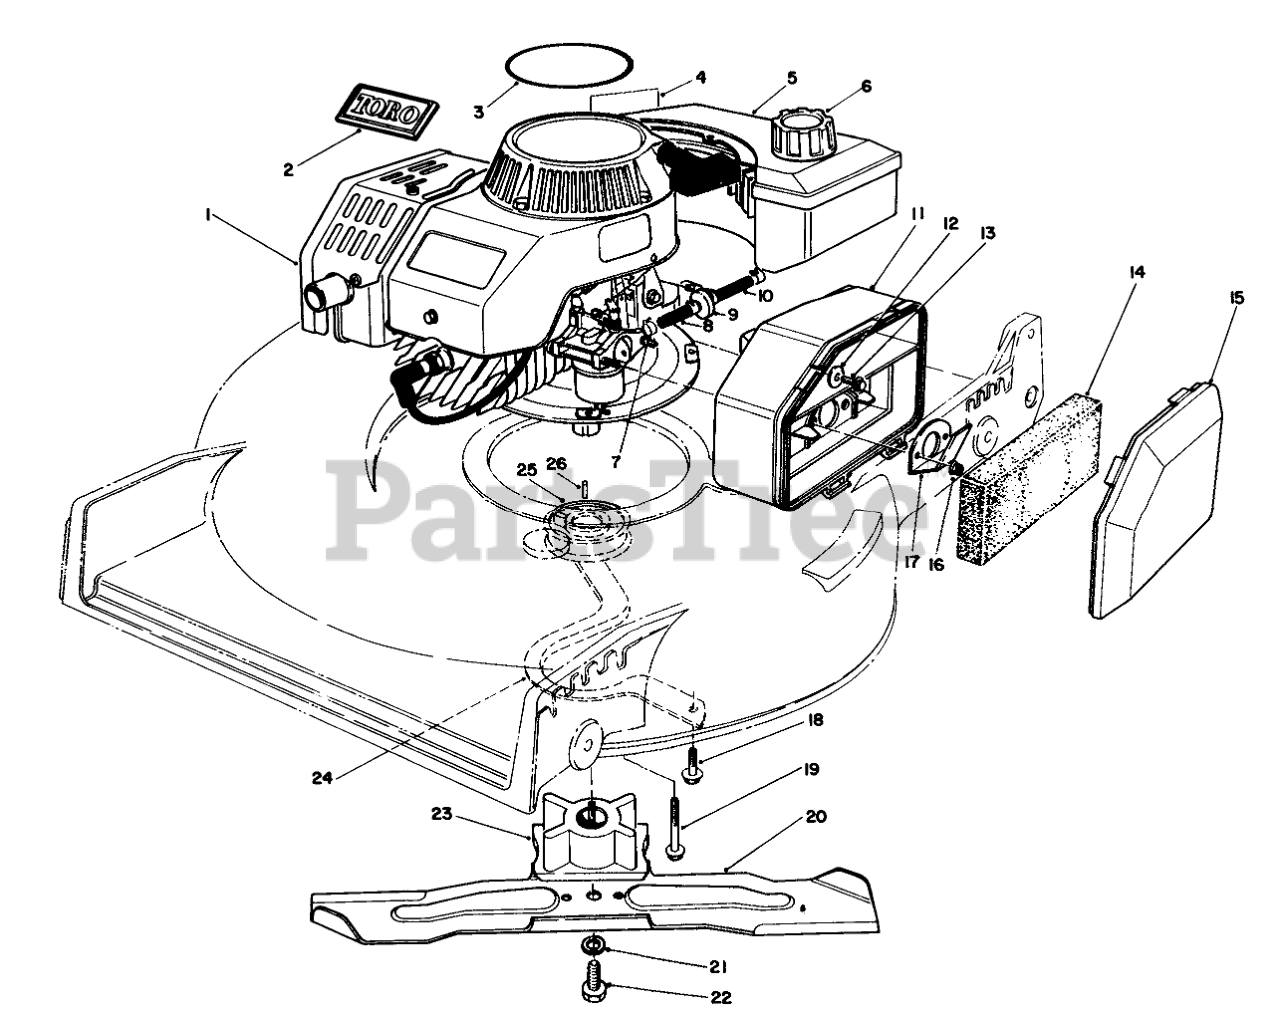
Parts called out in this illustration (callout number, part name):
1	Engine
2	TORO LOGO PLT
3	DECAL- 2 CYC RECOIL
4	Decal-Maintenance
5	Gas Tank Assembly
6	GAS CAP ASM
7	CLAMP-FUEL LINE
8	HOSE-FUEL
9	FILTER-FUEL
10	HOSE-FUEL
11	AIR CLEANER
12	WASHER-FLAT
13	SCREW-HH
14	FILTER
15	AIR CLEANER COVER
16	NUT-LOCK
17	SPIT BACK DEFLECTOR
18	Screw
19	SCREW-HHF
20	BLADE-21in
21	WASHER-LOCK
22	SCREW-BLADE
23	Retainer Blade
24	BELT GUIDE
25	PULLEY-DRIVER
26	KEY-SQUARE
